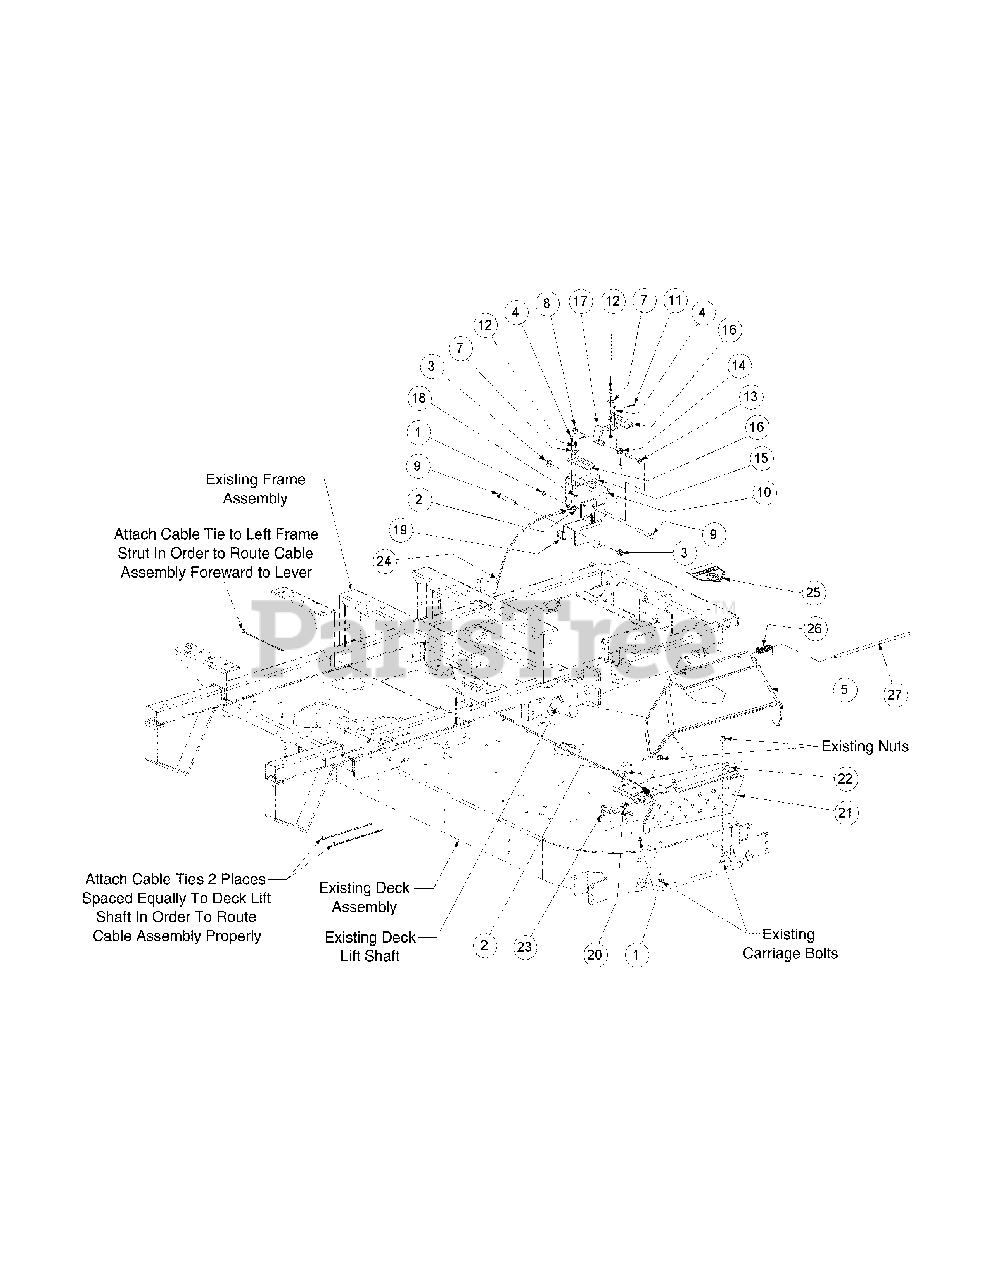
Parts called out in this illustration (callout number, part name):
1	Lock Nut, Nylon Insert, 1/4-20
2	Screw, Hex, Cap, 1/4-20 x .75
3	Hex Nut, Flange Lock, 3/8-16
4	Clevis Pin, 1/4 x 1/2, SS
5	Chute Deflector
6	Cable Tie
7	Bell Washer, .265 x 0.75 x 0.062
8	Hex Flange Lock Nut, 5/16-18
9	Hex Head Capscrew, 3/8-16 x 2.75
10	Spacer, .39 ID x .63 OD x 1.75
11	Cotter Pin, .072 x 1.12 Lg
12	Shoulder Bolt, 1/4 x 1/4, SS
13	Hex Head Capscrew, 5/16-18 x 2.5
14	Deck Lift Spring
15	Foot Pedal Latch Lever Assembly
16	Rate Plate Pad
17	Foot Pedal Latch Assembly
18	Nut w/ Star Washer, 10-24
19	Bracket Engage Cable Weldment
20	Restrictor Discharge Spring
21	Restrictor Discharge Weldment
22	Chute Deflector Bracket Weldment
23	Restrictor Support Weldment
24	Restrictor Discharge Cable Assembly
25	Decal, Danger, Hands & Feet
26	Torsion Spring, 0.4 ID x 2.16 LG.
27	Chute Deflector Rod
